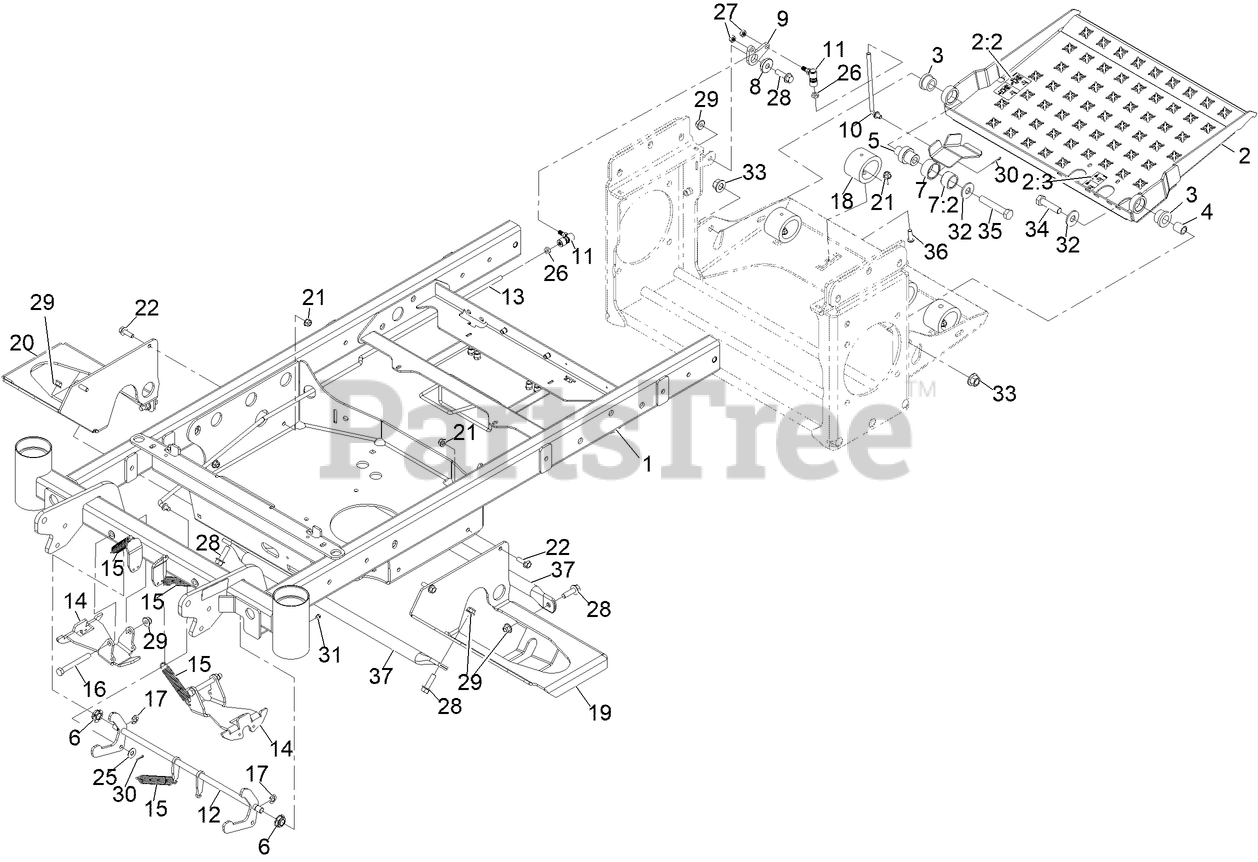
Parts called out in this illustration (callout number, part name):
1	FRAME-MAIN
2	FOOT PLATE W/DECALS
2:2	Decal-Spray Foot Button
2:3	Decal-Lock, Caster
3	BUSHING-RUBBER
5	PIVOT-PEDAL, CASTER
6	BEARING-SPHERICAL
7	PEDAL-LOCK, CASTER
7:2	BUSHING
8	PIVOT-FLANGE
9	CRANK-DEFLECTOR
10	LINKAGE-PEDAL, CASTER
11	Ball Joint-Quick Disconnect, SS
12	CRANK-LOCK, CASTER
13	LINKAGE-LOCK, CASTER
14	ARM-LOCK, CASTER
15	SPRING-EXTENSION
16	SCREW-HH
18	BUMPER-ISOLATOR
19	MOUNT-TANK, LOWER LT
20	MOUNT-TANK, LOWER RT
21	Nut-Hex Flange
22	SCREW-HHF
25	FLAT WASHER, 5/16 NOM,ST
26	Nut-Hex
27	NUT-LOCK, NI
28	SCREW-HHF
29	Nut-Hex Flange
30	COTTER PIN 5/64X3/4 18-8
32	WASHER-FLAT
33	Nut-Lock 1/2-13
34	SCREW-HH
35	SCREW-HH
36	SCREW-HSBH
37	TUBE-SUPPORT, LOWER
